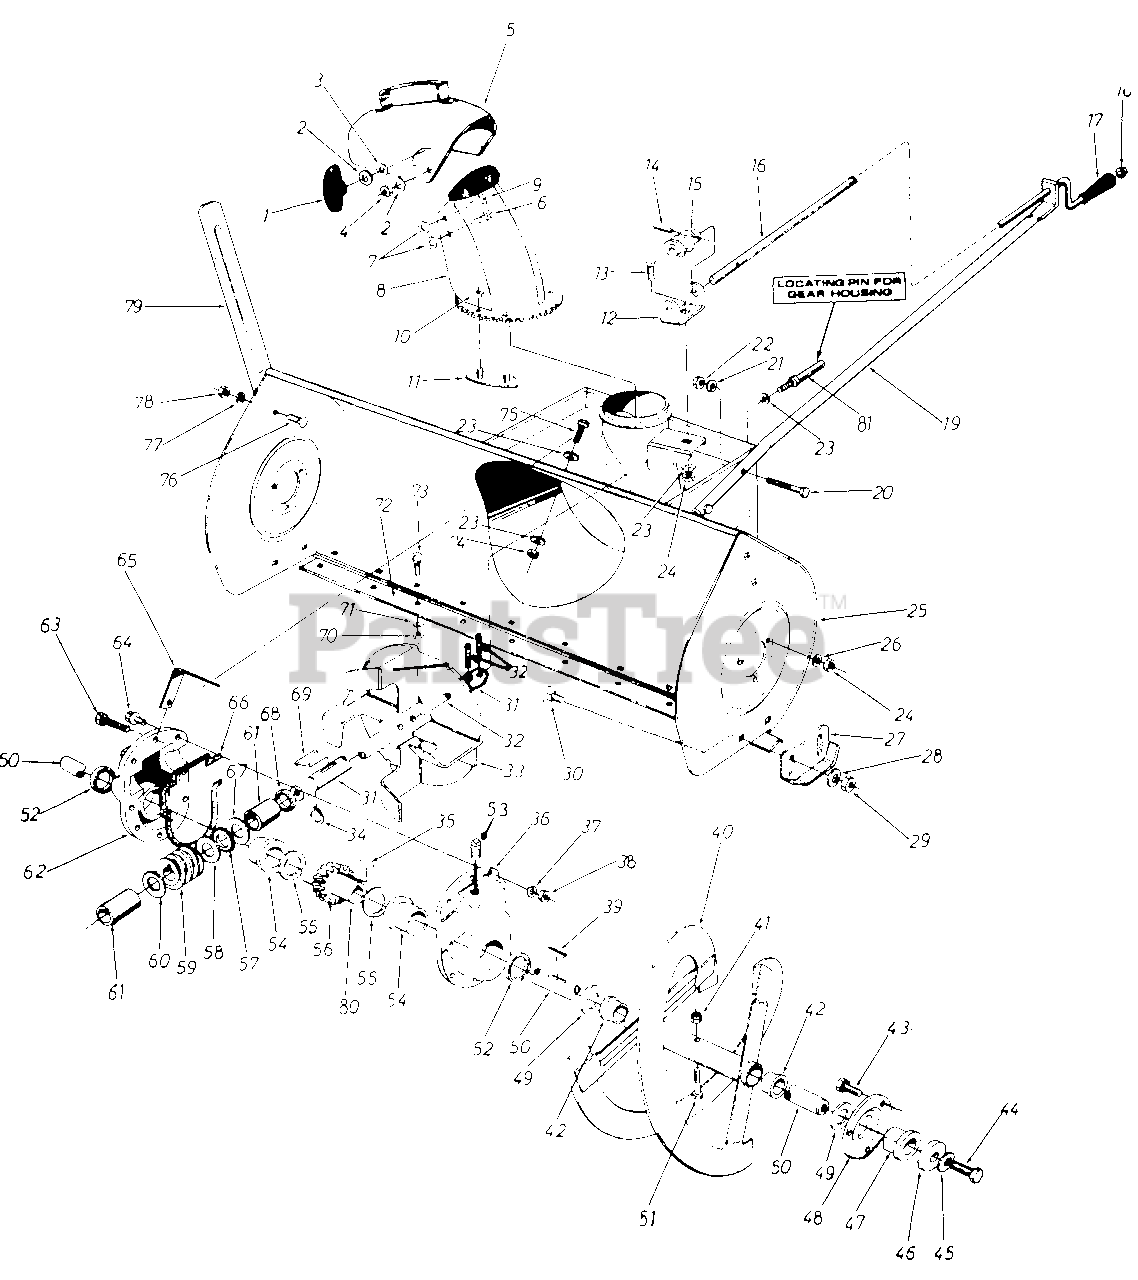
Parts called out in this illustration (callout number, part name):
1	Hand Knob Ass'y.
2	Bell. Wash. .345 I.D. x .88 O.D. x .060
3	Fl.-Wash. .312 I.D. x 1.125 0 O.D. x .125
4	Hex Cent. L-Nut 5/16-18 Thd.
5	Top Chute Ass'y .
6	Carriage Bolt 5/16-18 x 1.50" Lg.
7	Fl.-Wash. .53 I.D. x 1.25 0 O.D. x .100
8	Chute Ass'y.
9	Carriage Bolt 5/16-18 x 1.00" Lg.
10	Hex Cent. L-Nut 1/4-20 Thd.
11	Chute Flange Keeper Ass'y.
12	Chute Bracket
13	Carriage Bolt 5/16-18 x .62" Lg.
14	Spring Pin Roll 1/8" Dia. x .75" Lg.
15	Worm-R.H. w hree Threads
16	Chute Crank
17	Knob Black 3/8" Dia. Hole
18	Push Nut 3/8" rod.
19	Chute Crank Support Tubins
20	Hex Scr. 3/8-24 x 1.25" Lg.
21	L.-Wash. 3/8" Scr.*
22	Hex Ins. Jam L.-Nut 3/8- 0 24 Thd.
23	Bell.-Wash. .345 I.D. x .88 O.D. x .060
24	Hex Nut 5/16-18 Thd.
25	Blower Housing Assembly
26	L-Wash. 5/16" Scr.
27	Slide Shoe
28	Bell. Wash. .400 I.D. x .88 O.D. x .060
29	Hex Nut 3/8-16 Thd.
30	Carriage Bolt 3/8-16 x .75" Lg.
31	Blower Axle
32	Spring Pin Spiral 5/16" Dia. x 1.75" Lg.
33	Blower Fan Ass'y.
34	Snap Ring for .875" Dia. shaft
35	#91 Woodruff Key 1/4" x 3/4" Dia.
36	Gear Housing Half-L.H.
37	L.-Wash. 5/16" Scr.*
38	Hex Ins. L.-Nut 5/16-18 Thd.
39	#91 Woodruff Key 1/4" x 3/4" Dia.
41	Hex Ins. L-Nut 5/16-18 Thd
42	Plastic Bushing
43	Hex Sems Scr. 5/16-18 x .75" Lg.
44	Hex Scr. 5/16-18 x .88" Lg. Speco
45	Belleville Wash. .345" I.D. x .88" O.D.
46	Wash. .390 I.D. x 1.75" O.D. x 3/16" Thk.
47	Flange Bearing w/flats 1.00" I.D.
48	Bearing Housing
49	Fl-Wash. 1.00" I.D. x 1.75" O.D. x .100
50	Spiral Axle
51	Hex Scr. 5/16-18 x 1.75" Lg.
52	Oil Seal-1.50" I.D.
53	Sq. Hd. Pipe Plug 3/8" Thd.
54	Flange Bearing 1.503 I.D.
55	Fl.-Wash. 1.50" I.D. x 2.0" O.D. x .030
56	Double Threaded Worm Gear-L. H .
57	Thrust Bearing .88" I.D. x 1.44" O.D.
58	Fl.-Wash. .88" I.D. x 1.5" O.D. x .030
59	Double Threaded Worm-L.H
60	Fl.-Wash. .88 I.D. x 1.4" O.D. x .155
61	Sleeve
62	Gear Housing Half-R.H.
63	Hex Scr. 5/16-18 x 1.25" Lg. *
64	Hex Scr. 5/16-18 x 1.00" Lg.*
65	Gear Housing Support Brkt.
66	Rubber Gasket
67	Fl.-Wash. .88" I.D. x 1.4" O.D. x .155
68	Oil Seal. .875" I.D.
69	#9 Hi-Pro Key 3/16" x 3/4" Dia.
70	Hex Nut 5/16-18 Thd.
71	L.-Wash. 5/16" Scr.
73	Carriage Bolt 5/16-18 x .75" Lg.*
74	Hex Nut 5/16-18 Thd.*
75	Hex Scr. 5/16-18 x .75" Lg.
76	Carriage Bolt 5/16-18 x .62" Lg.*
77	L.-Wash. 5/16" Scr.*
78	Hex Nut 5/16-18 Thd.*
79	Guide Blade
80	Worm Gear Shaft
81	Stud 3/8-16 x 2.75" Lg.
